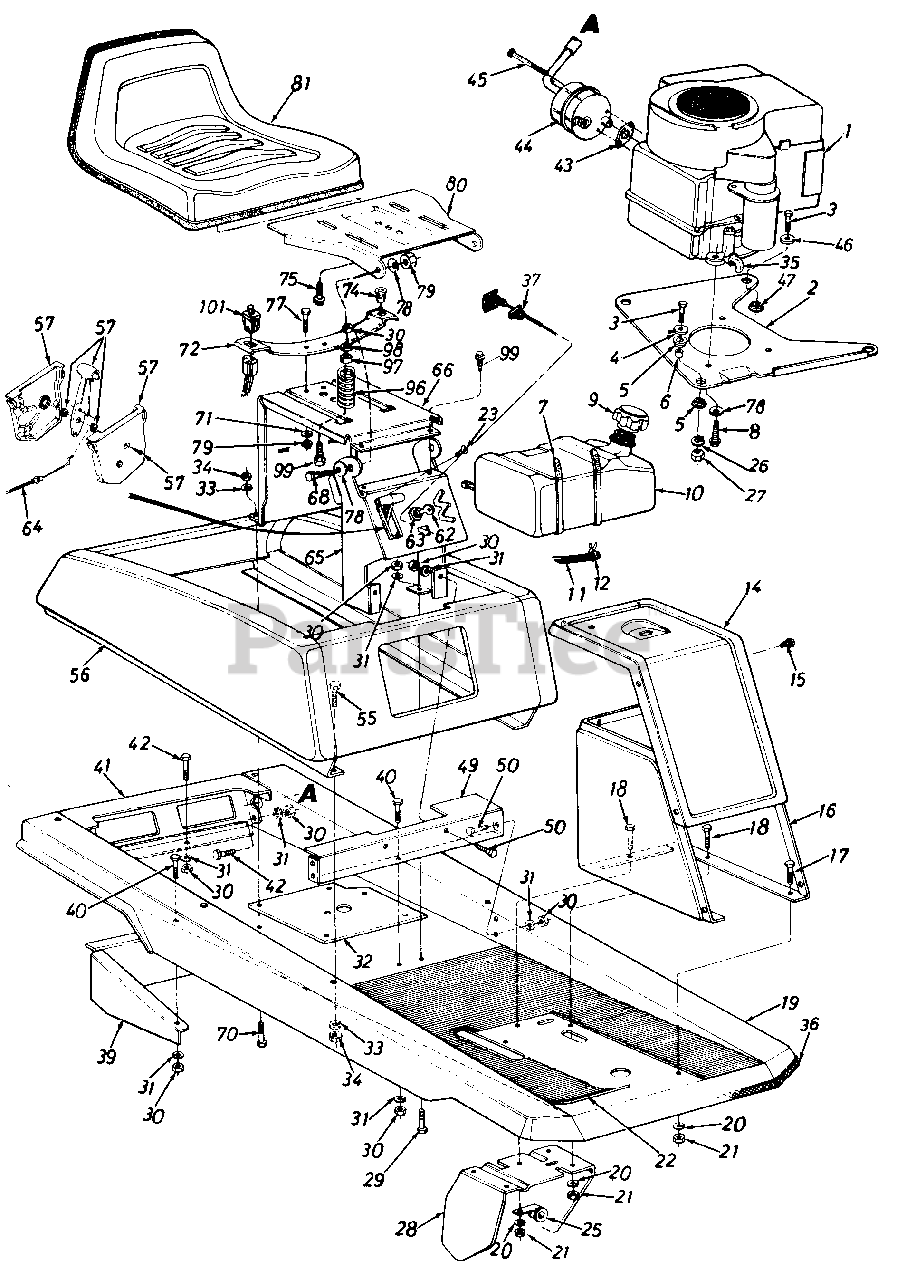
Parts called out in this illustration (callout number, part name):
1	Engine
4	Fl-Wash. .330" I.D. x 1.125" O.D.
5	Engine Mounting Grommet
6	Spacer .315" I.D. x .50" O.D. x.520" Lg.
7	Cable Tie 30.6 Lg.
8	Hex Wash. Hd. Self-Tap Scr. 3/8-16 x 1.25" Lg.
9	Gas Gauge
10	Fuel Tank (Black)
11	Fuel Line-26" Lg.
12	Hose Clamp-1/2" O.D. Tube
22	Floor Mat
23	Truss Mach. AB-Tap Scr. #10 x .50" Lg.
25	Clamp
26	L-Wash. 5/16" I.D.*
27	Hex Nut 5/16-24 Thd.*
28	Clutch-Brake Pedal Ass'y.
29	Hex Bolt 5/16-18 x .75" Lg*
30	Hex Nut 5/16-18 Thd.*
31	L-Wash. 5/16" I.D.*
34	Hex Nut 1/4-20 Thd.*
35	90ø Elbow Male To Female
36	Trim Strip 18" Lg.
37	Choke Control
43	Exhaust Gasket
44	Muffler Ass'y.
45	Shld. Bolt
46	Fl-Wash. .330" I.D. x 1.25" O.D.
47	Flange Wash. .320" I.D. x .750" O.D.
49	Seat Support & Frame Brkt.
50	Hex Bolt 5/16-18 x .75" Lg.
55	Hex Bolt 1/4-20 x .50 Lg.
57	Throttle Control Box Ass'y.
62	Ignition Key
63	Ignition Switch
64	Throttle Control Wire
70	Hex Tap Scr. 1/4-20 x 1.0" Lg.
71	L-Wash. 5/16" I.D.
72	Seat Spring
74	Grommet
75	Hex Wash. Hd. Tap Scr. 3/8-16 x 3/4" Lg.
77	Hex Bolt 5/16-18 x .75" Lg.
78	Bell-Wash. .345" I.D. x .88" O.D.
79	Hex Cent. L-Nut 5/16-18 Thd.
80	Seat Pivot Bracket
81	Seat Ass'y. Comp.
96	Compression Spring 2.7" Lg.
97	Bushing
98	Fl-Wash. .344" I.D. x .875"
99	Hex Bolt 5/16-18 x 1" Lg. (Grade 5)
101	Seat Switch
